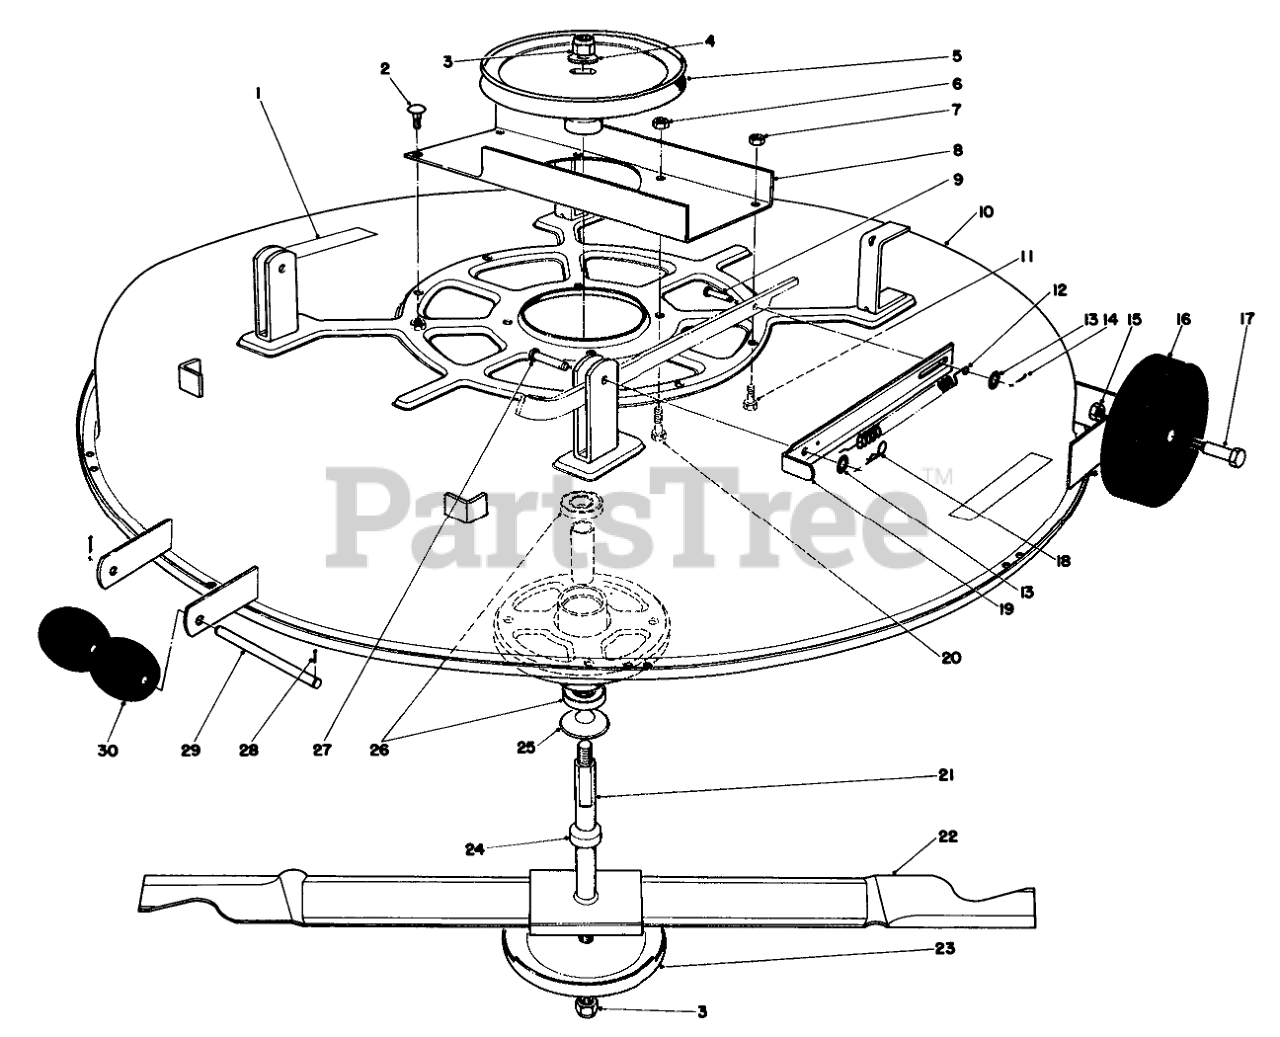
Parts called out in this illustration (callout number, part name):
1	Caution Decal
2	SCREW-CARR
4	Thrust Washer
5	BLADE DRIVE PULLEY
6	NUT-LOCK, CONE
7	NUT-HEX, SIDE DEFORM
8	REINFORCEMENT CHANNEL
9	PIN-CLEVIS
10	Mulcher Deck
11	SCREW-HH
12	DECK TENSION SPRNG O
13	WASHER-FLAT
14	PIN-COTTER
15	Nut
16	DECK WHEEL
18	PIN-COTTER
19	DECK SPRING STRAP R
20	SCREW-HH
21	Spindle Assembly (Incl. Ref. #24-26)
22	Blade
23	Cup
24	SPACER
25	DUST COVER
26	BEARING
27	PIN-CLEVIS
28	PIN-COTTER
29	ROLLER SHAFT
30	ROLLER
